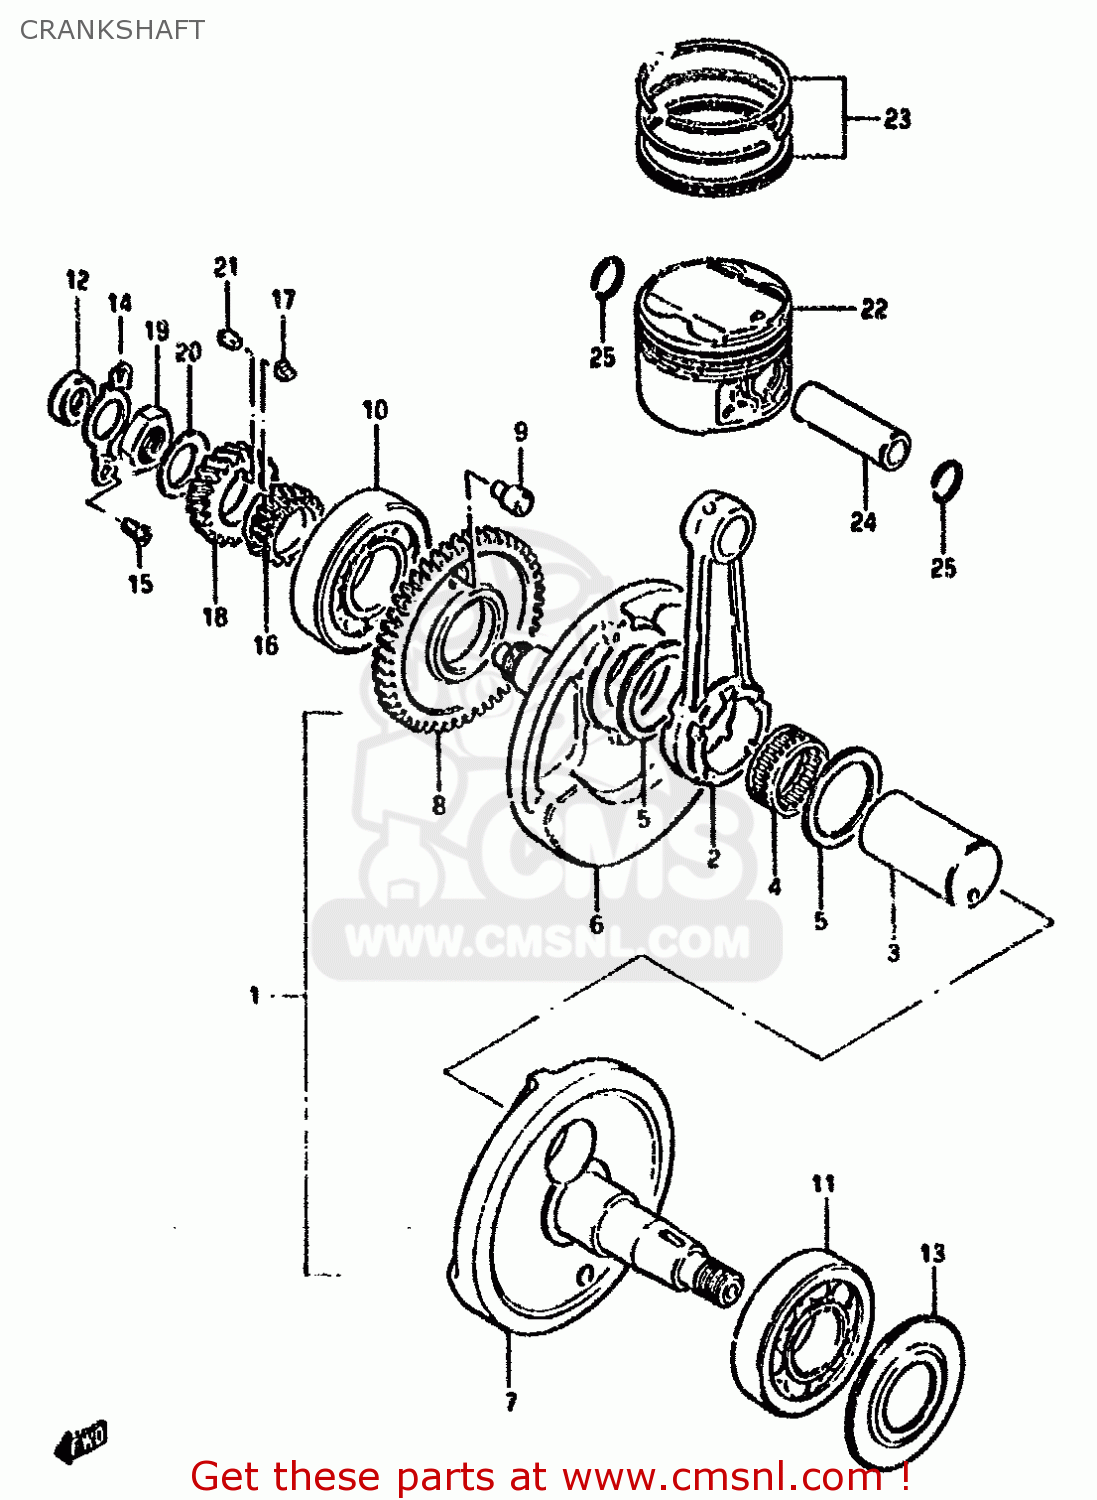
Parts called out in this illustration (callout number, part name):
1	CRANKSHAFT ASSEMBLY
2	ROD,CONNECTING
3	PIN,CRANK
4	BEARING(31X39X21)
5	WASHER(31X48.5X1)
6	CRANKSHAFT,R
7	CRANKSHAFT,LEFT
8	GEAR,CRANK BALANCER DRIVE
9	PIN
10	BEARING(30X72X19)
11	BEARING(35X80X21)
12	SEAL,OIL(14X26X6)
13	WASHER,CRANKSHAFT OIL SEALING
14	RETAINER,CRANKSHAFT BEARING,R
15	SCREW
16	SPROCKET,CAM CHAIN DRIVE(NT:21
17	KEY,SPROCKET
18	GEAR,PRIMARY DRIVE NO.21
19	NUT (20MM)
20	WASHER
21	KEY
22	PISTON
23	RING SET,PISTON
25	CIRCLIP,PISTON PIN
